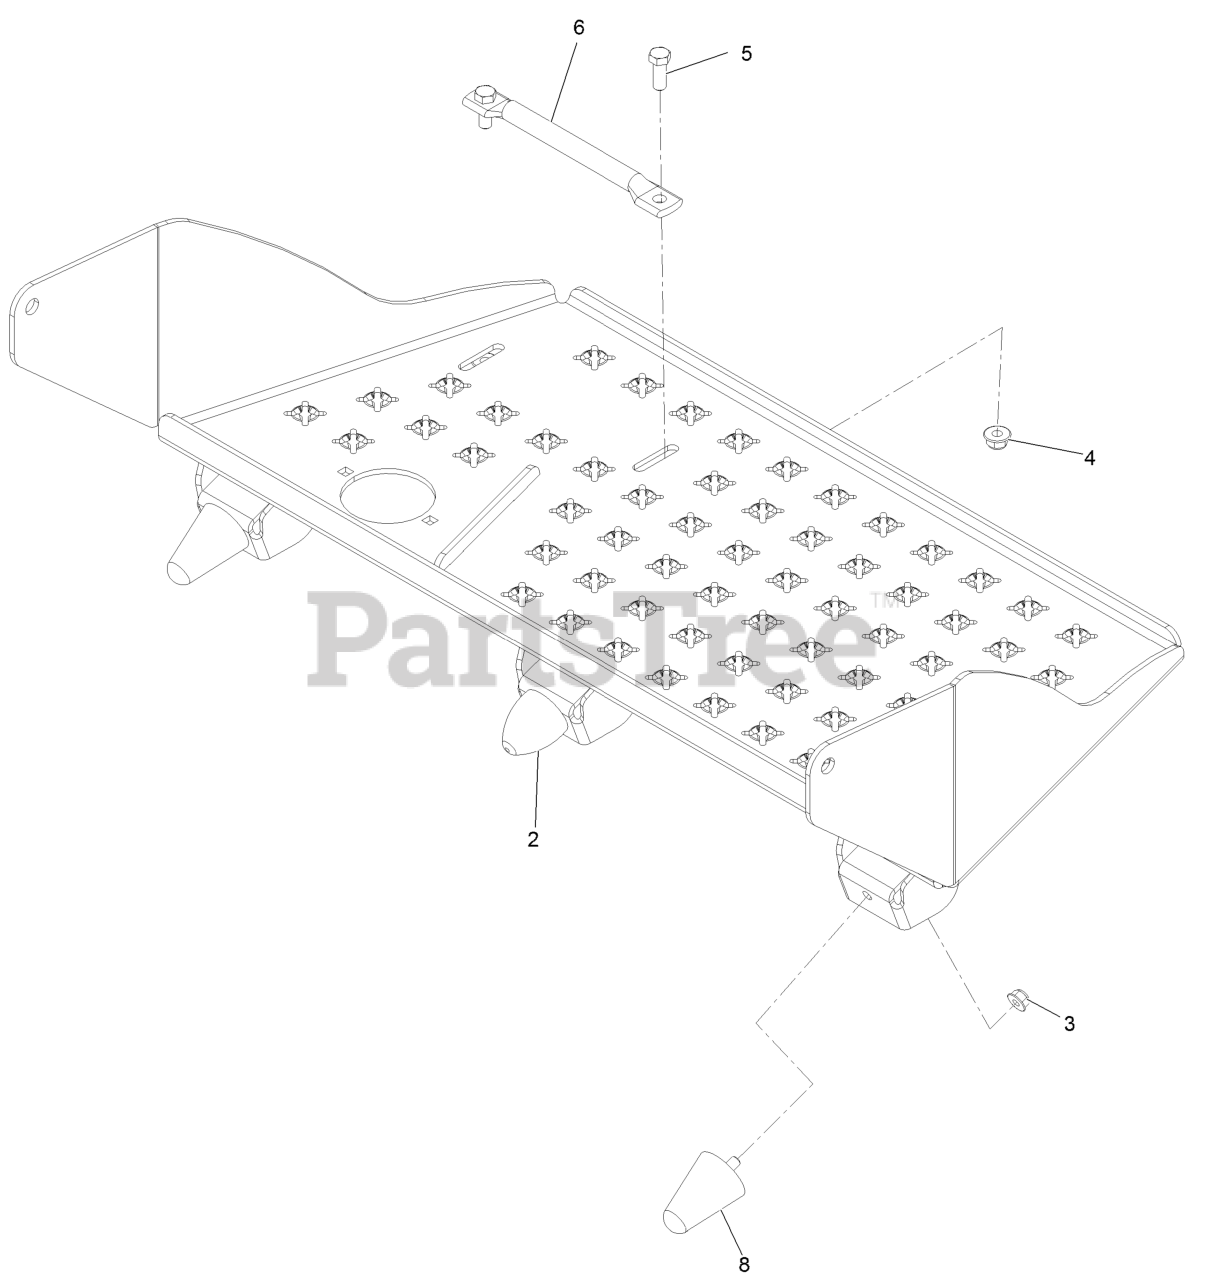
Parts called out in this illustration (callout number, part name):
2	BUMPER-RUBBER
3	NUT-HF, NI
4	NUT-HF, NI
5	SCREW-HH
6	ROCKER-FOOT PEDAL
8	BUMPER-RUBBER
